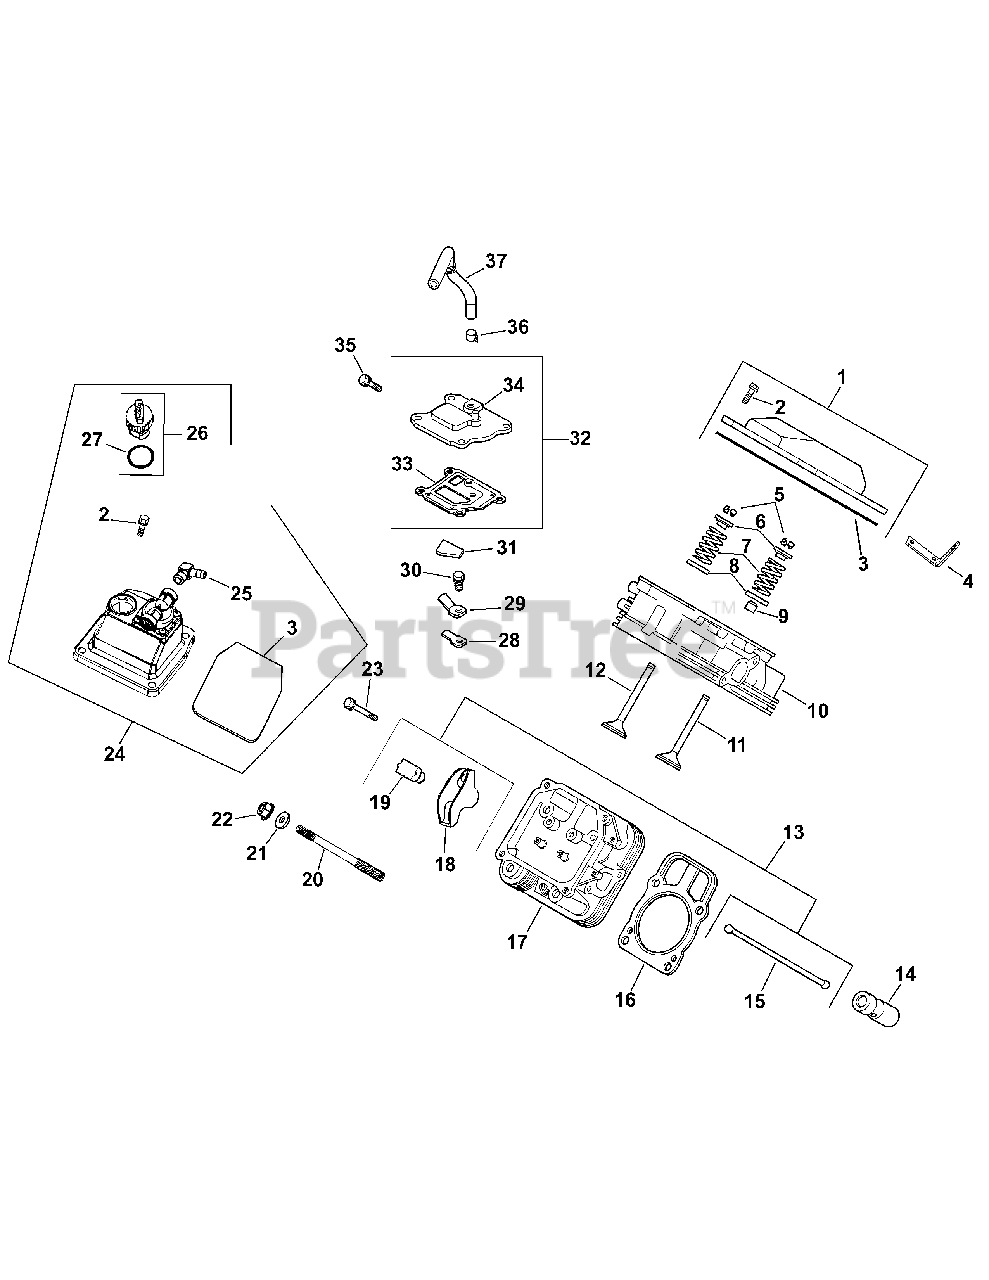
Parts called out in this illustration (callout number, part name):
1	Kit, valve cover - plain (Includes 2,3)
2	Screw, hex. flange M6x1.0x30 (4)
3	O-Ring, valve cover
4	Strap, lifting
5	Kit, retainer (4)
6	Cap, valve spring (4)
7	Spring, valve (4)
8	Retainer, spring (4)
9	Seal, valve stem (2)
10	Head assembly, #1 cylinder
11	Valve, intake (Std.) (2)
11	Valve, intake (.25) (2)
12	Valve, exhaust (Std.) (2)
12	Valve, exhaust (.25) (2)
13	Kit, valve train (Includes 15,18,19)
14	Lifter, valve (4)
15	Rod, push (4)
16	Kit, cylinder head gasket (Includes 21,22) (2)
17	Head assembly, #2 cylinder
18	Arm, rocker (4)
19	Pivot, rocker arm (4)
20	Stud, cylinder head (8)
21	Washer, plain (8)
23	Screw, hex. flange M6x1.0x34 (4)
24	Kit, fuel pump valve (Includes 2,3,25-27)
25	Fitting, 90° (2)
26	Cap assembly, oil fill (Includes 27)
27	O-Ring
28	Reed, breather
29	Retainer, breather reed
30	Screw, hex. flange M5x0.8x10
31	Filter, breather
32	Kit, breather (Includes 33,34)
33	Gasket, breather
34	Cover, breather
35	Screw, hex. flange M6x1.0x20 (4)
36	Clamp, breather
37	Hose, breather
